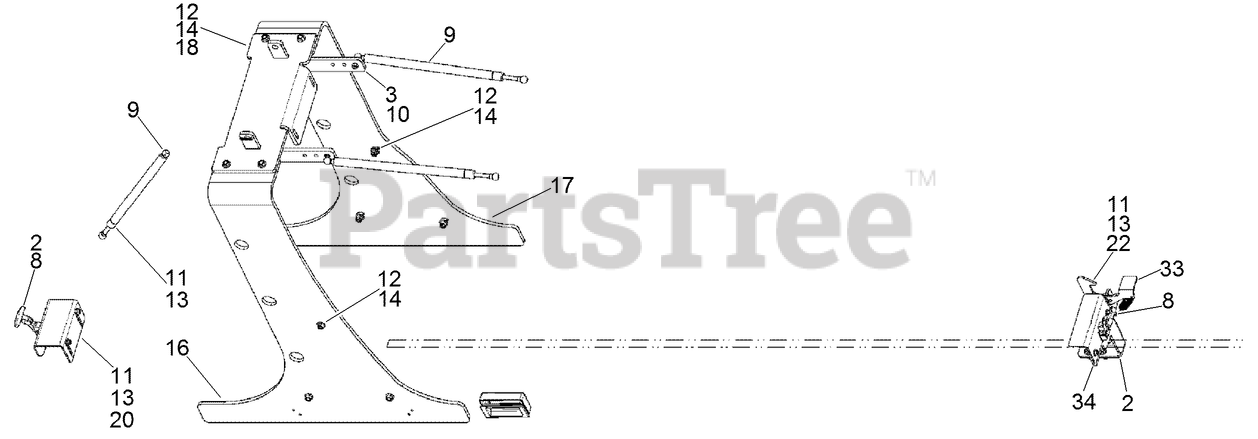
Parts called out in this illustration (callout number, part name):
2	RIVET - Blind Brk Mdrl .187 x .700 in ZND
3	NUT - Prev Trq 5/16 GRB ZND Direct
8	LATCH - Flexible Draw
9	SPRING-GAS
10	STUD-BALL
11	NUT-TORQUE, PREVAILING
12	NUT-FLANGE, NYLOCK
13	SCREW-HH
14	SCREW-HH
16	PLATE - Hood Mount
17	PLATE - Hood Mount
18	ASSEMBLY - Shroud Support
20	STOP - Rear Hood
22	STOP - Front Hood
33	LATCH - Hood Safety
34	MOUNT - Hood Safety Latch
